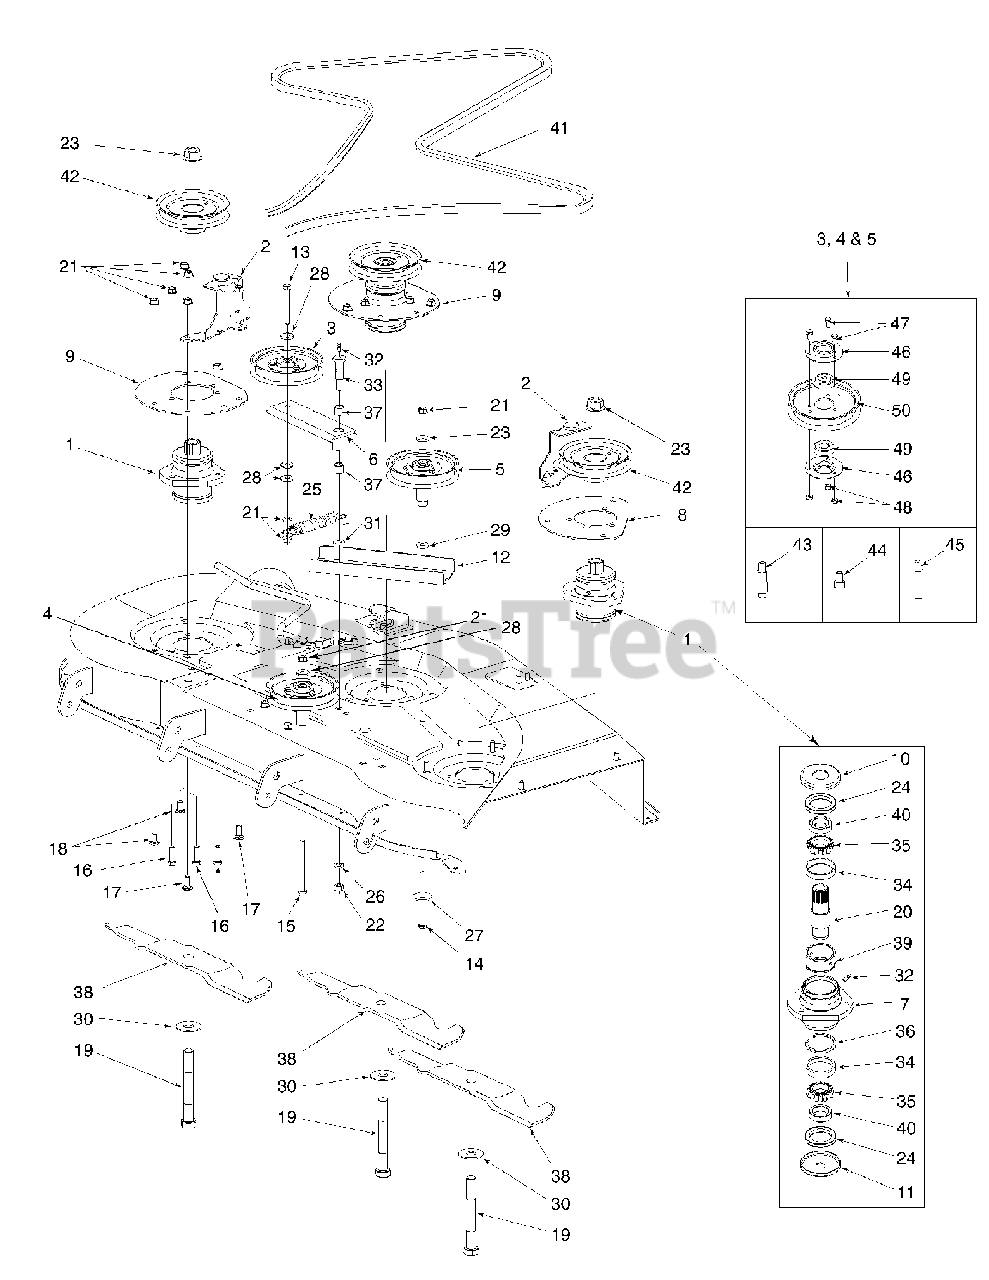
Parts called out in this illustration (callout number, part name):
1	Spindle Ass'y, Complete
2	Bracket, Belt Cover Support
3	Pulley Ass'y, 5" Idler [Includes Ref. No. 44 & 46 Thru 50]
4	Pulley Ass'y, 5" Idler [Includes Ref. No. 45 & 46 Thru 50]
5	Pulley Ass'y, 5" Idler [Includes Ref. No. 43 & 46 Thru 50]
14	Screw, Hex Cap, 3/8-16 x 4.5 GR5
15	Screw, Hex Cap, 3/8-16 x 4.25 GR5
16	Screw, Hex Cap, 3/8-16 x 1.25 GR5
17	Bolt, Carriage, 3/8-16 x 1.0 GR5
18	Bolt, Carriage, 3/8-16 x .75 GR5
19	Bolt, Hex Head, 3/4-16 x 6.0
20	Shaft, Spindle
21	Nut, Hex Flange Lock, 3/8-16
22	Nut, Hex, 7/16-14
23	Nut, Hex Flange, 3/4-16
24	Oil Seal
25	Spring, Extension
26	Washer, Lock, 7/16
27	Washer, Flat, 3/8 x 1.5 x .134
28	Washer, Flat, .385 x 1.0 x .135
29	Washer, Flat
30	Washer, Flat, .78 x 2.0 x .105
31	Washer, Flat, .469 x .875 x .105
32	Fitting, Grease
33	Shoulder Bolt
34	Cup, Bearing
35	Bearing, Cone
36	Spacer, Bearing
37	Bearing, Sleeve
38	Mower Blade
39	Spacer, Bearing Cup
40	Ring, Seal
41	V-Belt, B Section 161.0 Lg
41	V-Belt, B Section 165.0 Lg Liquid Cooled Units Only
42	Pulley, Spindle
43	Spacer, Front Deck Idler Pulley
44	Spacer, Idler Arm Pulley
45	Spacer, Rear Deck Idler Pulley
46	Cup, Bearing
47	Screw, Hex Cap, 1/4-20 x .62 GR5
48	Nut, Hex Insert Lock, 1/4-20
49	Bearing, Ball
50	Pulley, Flat Idler
